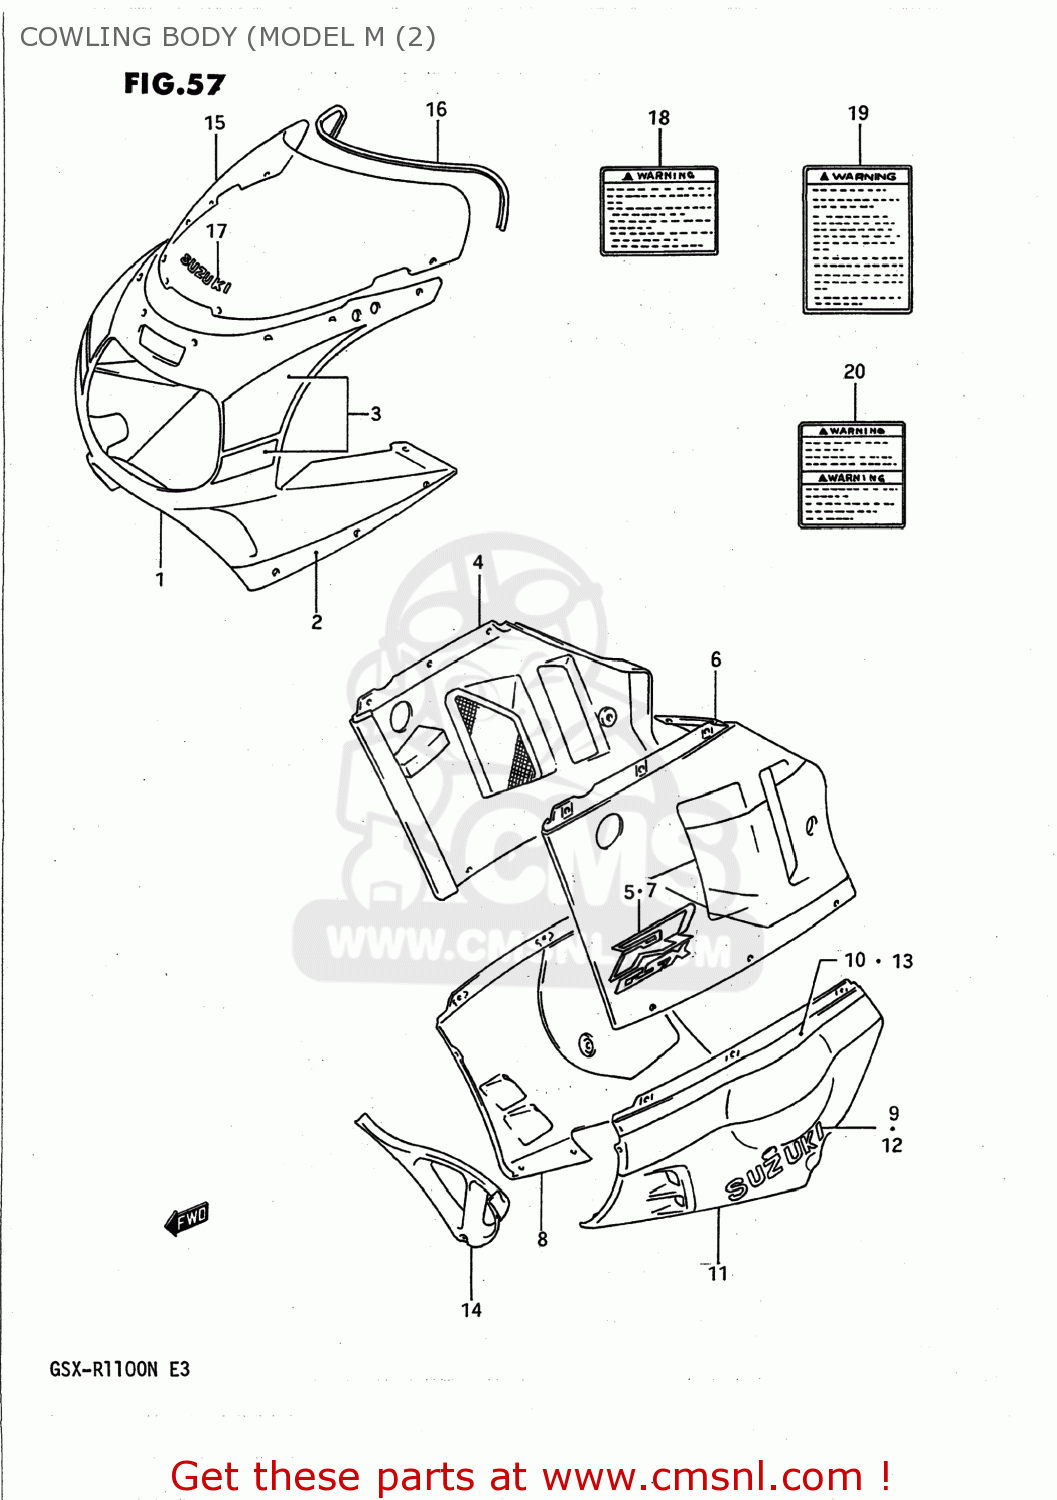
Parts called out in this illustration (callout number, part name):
1	BODY ASSY,COWLING
2	TAPE SET,COWLING,UPPER
3	TAPE SET,COWL UPR FR
4	COVER COMP,COWLING SIDE,RIGHT
5	EMBLEM,COWLING SIDE
6	COVER COMP,COWLING SIDE,LEFT
7	EMBLEM,COWLING SIDE
8	COWLING,UNDER,R
9	EMBLEM,SUZUKI
10	TAPE,COWLING,UNDER STRIPE
11	COWLING COMP,UNDER,LEFT
12	EMBLEM,SUZUKI
13	TAPE,COWLING,UNDER STRIPE
14	COWLING,UNDER,CENTER
15	SCREEN SET,WIND
16	MOLDING
17	EMBLEM,SUZUKI(WHITE)
18	LABEL
19	LABEL (WARNING SCREEN)
20	LABEL (WARNING)
